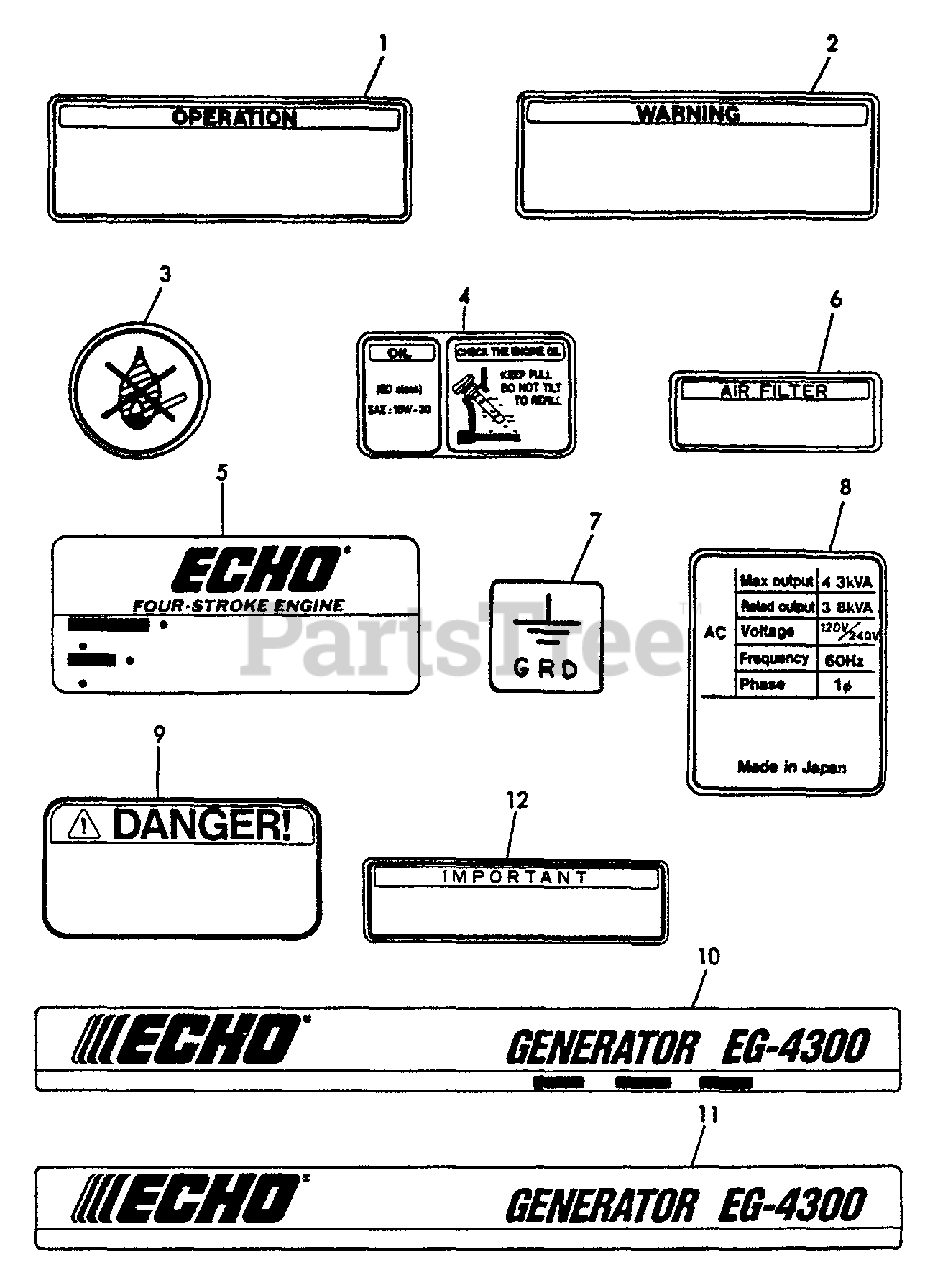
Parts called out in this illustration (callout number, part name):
1	LABEL - OPERATION
2	LABEL - WARNING
3	LABEL - NON FIRE
4	LABEL - OIL
5	LABEL - ECHO
6	LABEL - AIR CLEANER
7	LABEL - GROUND
8	LABEL - GENERATOR
9	LABEL - DANGER
10	LABEL - GENERATOR
11	LABEL - GENERATOR
12	LABEL - IMPORTANT
